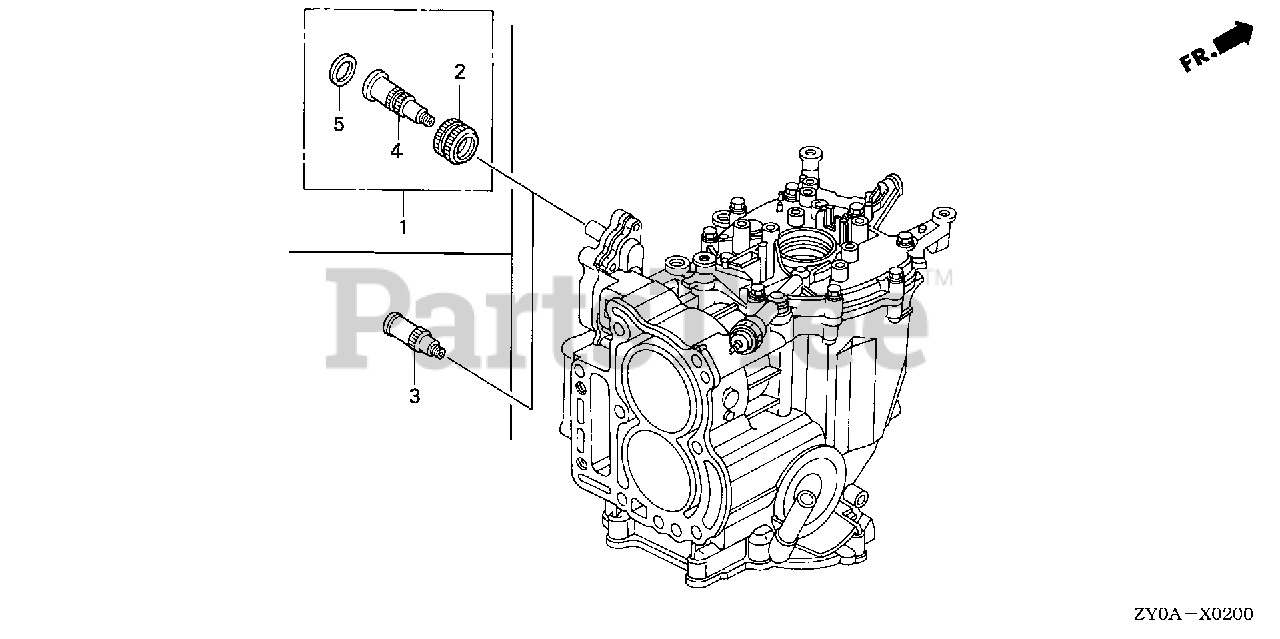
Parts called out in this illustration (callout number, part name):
1	JOINT KIT, WATER HOSE
2	NUT, WATER MOUTH
3	JOINT, WATER HOSE
4	JOINT, WATER HOSE
5	SEAT, WATER MOUTH
